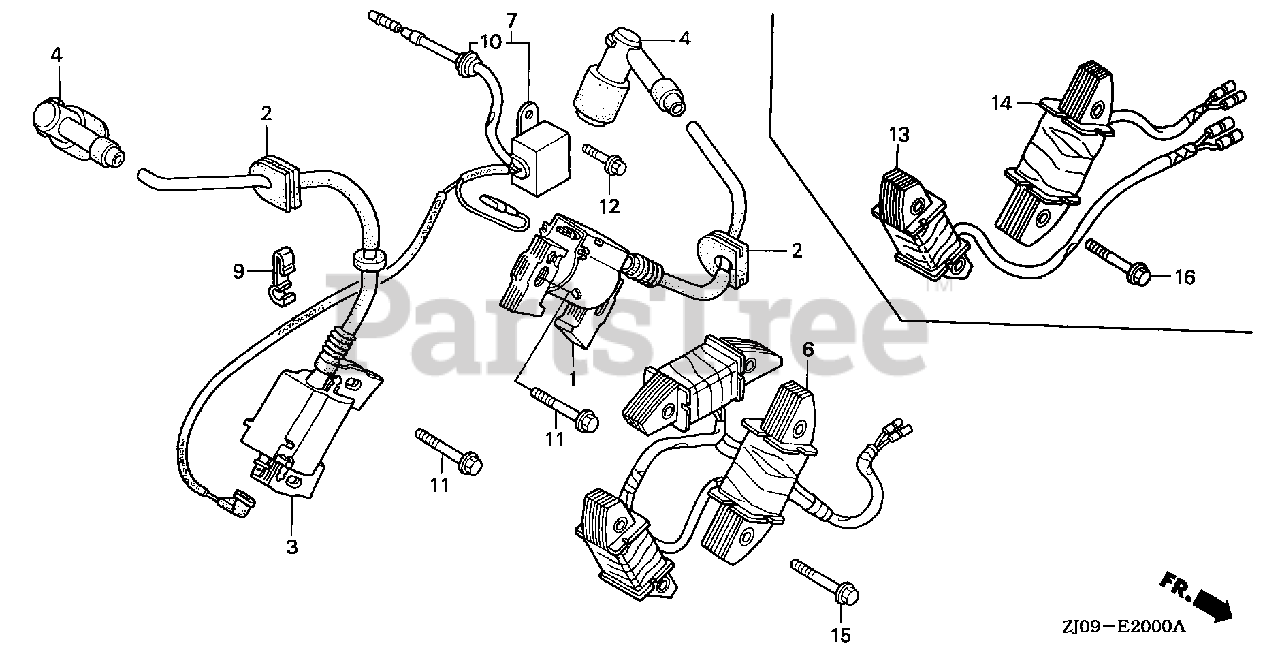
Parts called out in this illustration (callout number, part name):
1	COIL ASSY., R. IGNITION
2	GROMMET, IGNITION WIRE
3	COIL ASSY., L. IGNITION
4	CAP ASSY., NOISE SUPPRESSOR
6	COIL ASSY., CHARGE (12V/20A)
7	DIODE ASSY., ENGINE STOP
9	CLAMP, WIRE
10	GROMMET, TOOL
11	BOLT, FLANGE (6X32)
12	BOLT, FLANGE (6X8)
15	BOLT, FLANGE (6X32)
